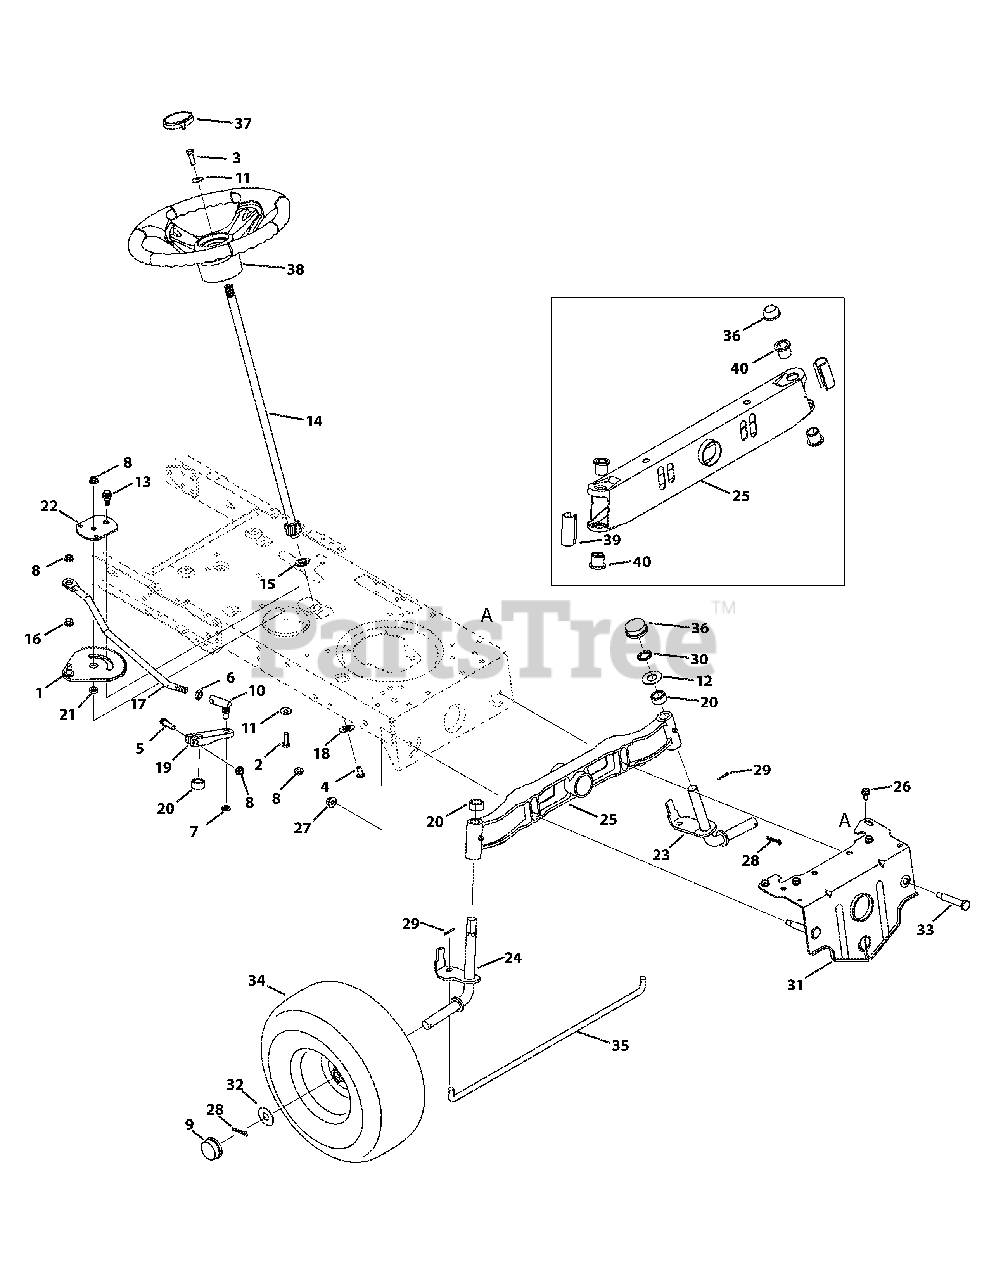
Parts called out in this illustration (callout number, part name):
1	Gear Assembly, Steering
2	Screw, 5/16-18, 1.00, Gr5
3	Screw, 5/16-18, 1.00, Gr5, Lock
4	Screw, Mach, 5/16-18, 0.750
5	Screw, 5/16-18, 1.75, Gr5
6	Nut, Jam, 7/16-20, Gr2
7	Nut, Hex Lock, 3/8-24
8	Nut, Flange Lock, 5/16-18, Grf
9	Hub Cap
10	Ball Joint, 7/16-20, Lock
11	Washer, Bell, .340 x .872 x .060
12	Washer, Flat, .78 x 1.59 x .60
13	Shoulder Screw, .435 x .3485, 5/16-18
14	Steering Shaft, 5/8 Spline x 21.86
15	Bearing, Flange, Hex 5/8
16	Flange Bearing .375 ID x .5 OD
17	Drag Link, Steering
18	Cap, 1.25 x .16
19	Steering, Block
20	Spacer, .710 ID x .125 OD x .56
21	Spacer, .322 ID x .625 OD x .21
22	Stabilizer Plate, Gear Segment
23	Axle Assmbly LH (38" & 42" Deck)
23	Axle Assembly, LH (46" Deck)
24	Axle Assmbly RH (38" & 42" Deck)
24	Axle Assembly, RH (46" Deck)
25	Pivot Bar, Cast
25	Pivot Bar
26	Screw, 5/16-18, 0.750
27	Nut, Flange Lock, 3/8-16, GrF
28	Pin, Cotter, 5/32, 1.25
29	Pin, Cotter, 1/8 x 0.75
30	Push Nut 3/4 Dia.
31	Pivot Bar Bracket
32	Washer, Flat, .781 x 1.59
33	Scr., Shlder, .500 x 2.380, 3/8-16
34	Wheel Ass’y, Sq. Shldr., 15 x 6 x 6 Grey
34	Wheel Ass’y, Sq. Shldr., 15 x 6 x 6 Yellow
34	Wheel Ass’y, Sq. Shldr., 15 x 6 x 6.5
35	Tie Rod
36	Push Cap, Cast
36	Push Cap
37	Cap, Steering Wheel (Sprig Logo)
37	Cap, Steering Wheel (No Sprig)
38	Steering Wheel, Standard Grip
39	Standard Axle Cap
40	Bearing., Flange.
